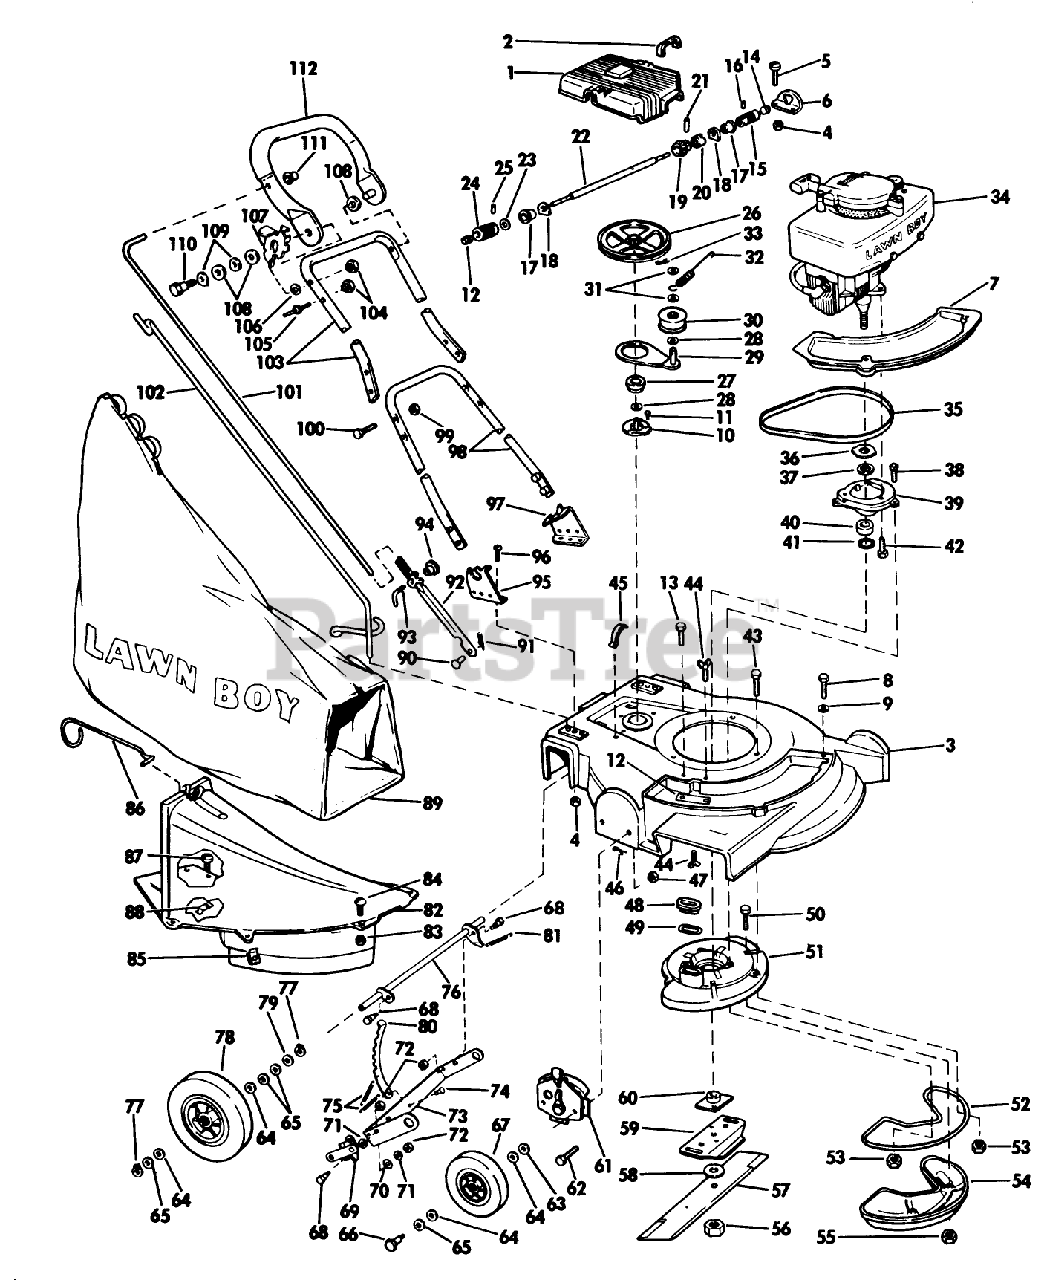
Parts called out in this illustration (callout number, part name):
8	SCREW SEMS TRM HEX HD
14	GREASE PLUG
26	PULLEY&OILER FELT (13)
49	GASKET S
55	LOCKNUT E
56	NUT-BLADE
60	PLATE AND COLLAR ASM
63	WASHER WROUGHT
66	BOLT WHEEL
68	BOLT RB&W
71	WASHER S
72	STOP NUT
77	RETAINING RING
82	Skirt Assembly
85	SPEED NUT ARDEN
89	89802 LB WHOLE GOODS
96	SCREW S
108	WASHER M
110	BOLT PIONEER
